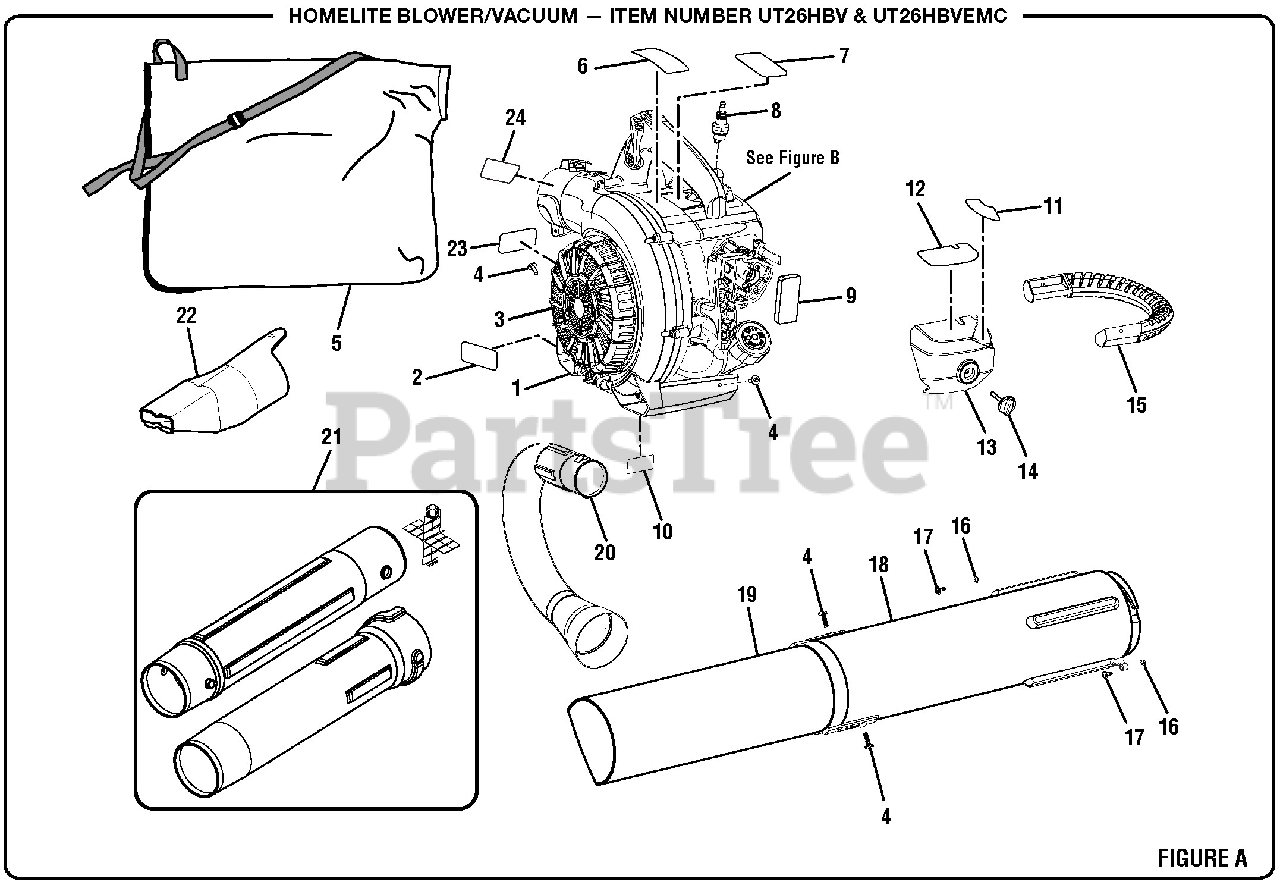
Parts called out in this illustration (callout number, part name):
1	Vacuum Door Spring
2	Combustion Label
3	Vacuum Door
4	Vacuum Tube Screw (10-14 x 1/2 in.)
5	Vacuum Bag w/Shoulder Strap
6	Warning Label
7	Logo Label (Small)
8	Spark Plug (L7RTC)
10	EMC Label (UT26HBVEMC only)
11	Choke Label
12	Starting Label
13	Air Filter Cover
15	Vacuum Handle
17	Screw (1/4-20 x 3/4 in.)
18	Upper Vacuum Tube
19	Lower Vacuum Tube
20	Vacuum Bag Adaptor
21	Blower Tube Assembly
22	Wet Leaf Nozzle
23	Hot Surface Label
24	Tube Removal Label
